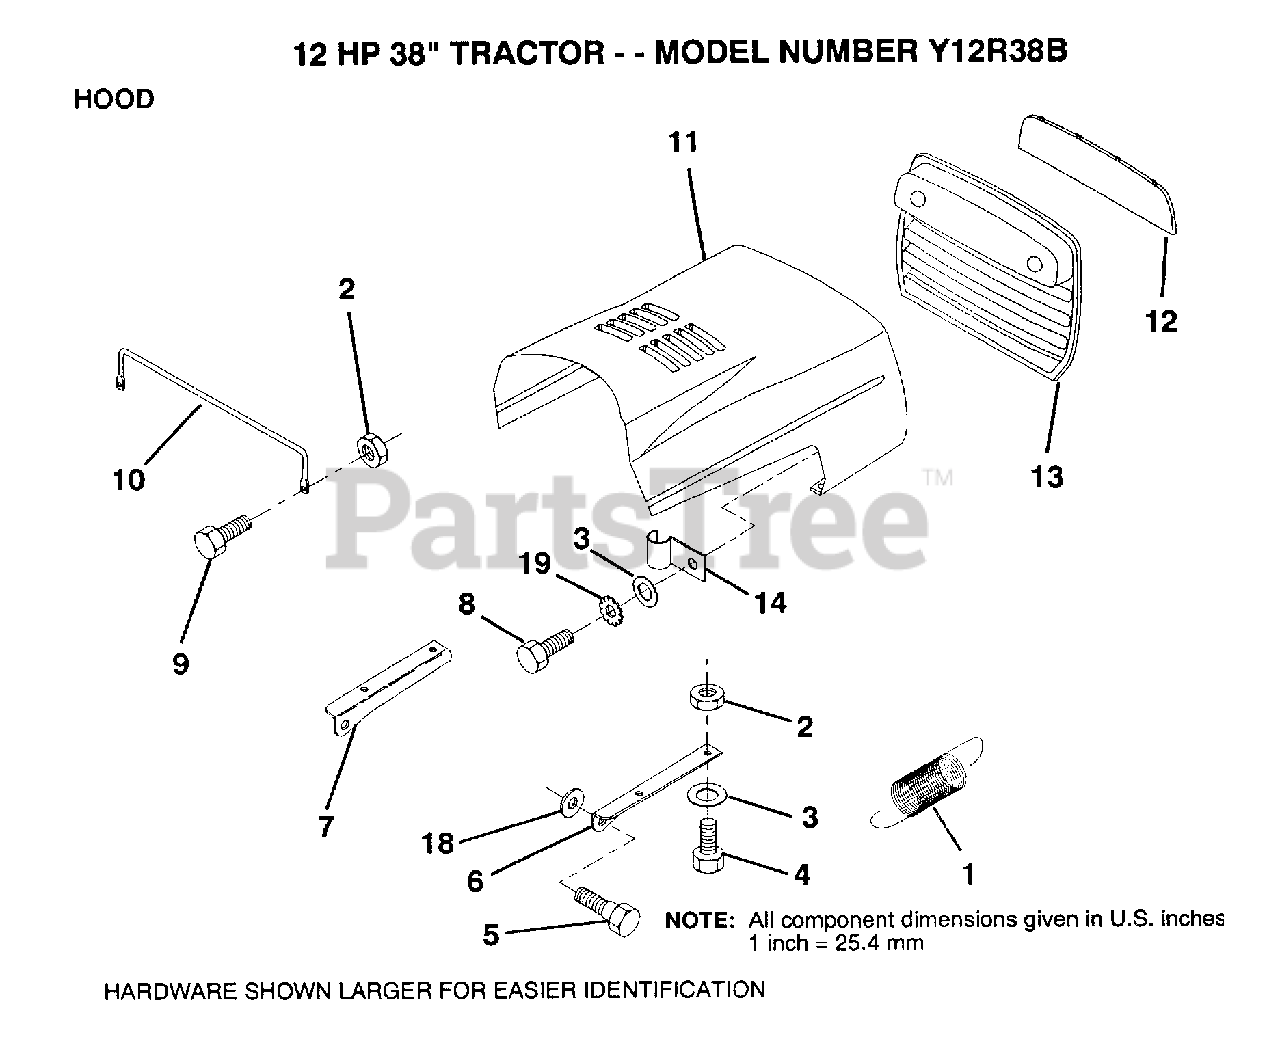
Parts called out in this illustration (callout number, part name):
1	EXT SPRING
2	NUT
3	WASHER
4	BOLT
6	BRKT HOOD RH
7	BRKT HOOD LH
10	"BRACE,HOOD"
11	HOOD
12	LENS
13	GRILL
14	CLIP T
18	WASHER
19	LOCKWASHER GT
